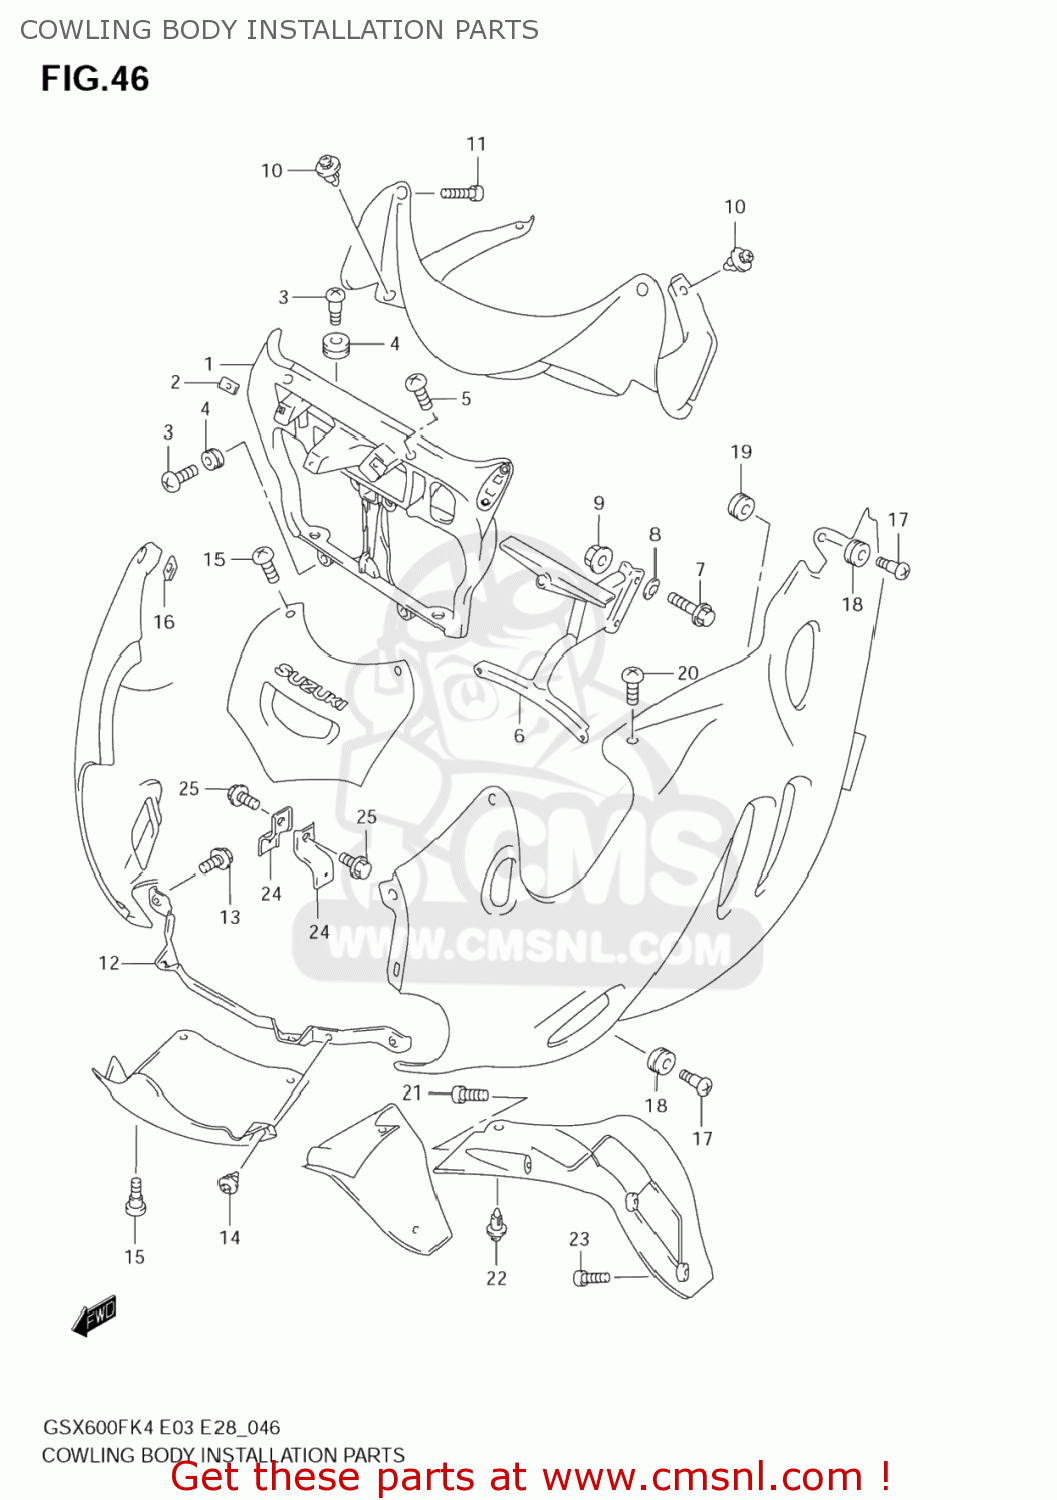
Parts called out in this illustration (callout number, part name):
1	BRACE,COWLING FR
2	NUT,COWL
3	SCREW(6X20)
4	CUSHION
5	SCREW
6	BRACE,COWLING RR
7	BOLT(8X40)
8	WASHER
9	NUT
10	CLIP(BLACK)
11	SCREW
12	BRACKET,PANEL CTR LWR
13	BOLT
14	CLIP(BLACK)
15	SCREW(5X16)
16	NUT
17	SCREW(6X20)
18	CUSHION
19	CUSHION
20	SCREW(5X16)
21	SCREW(4X10)
22	CLIP(BLACK)
23	SCREW
24	BRACKET,COWLING SIDE LWR
25	BOLT(6X12)
